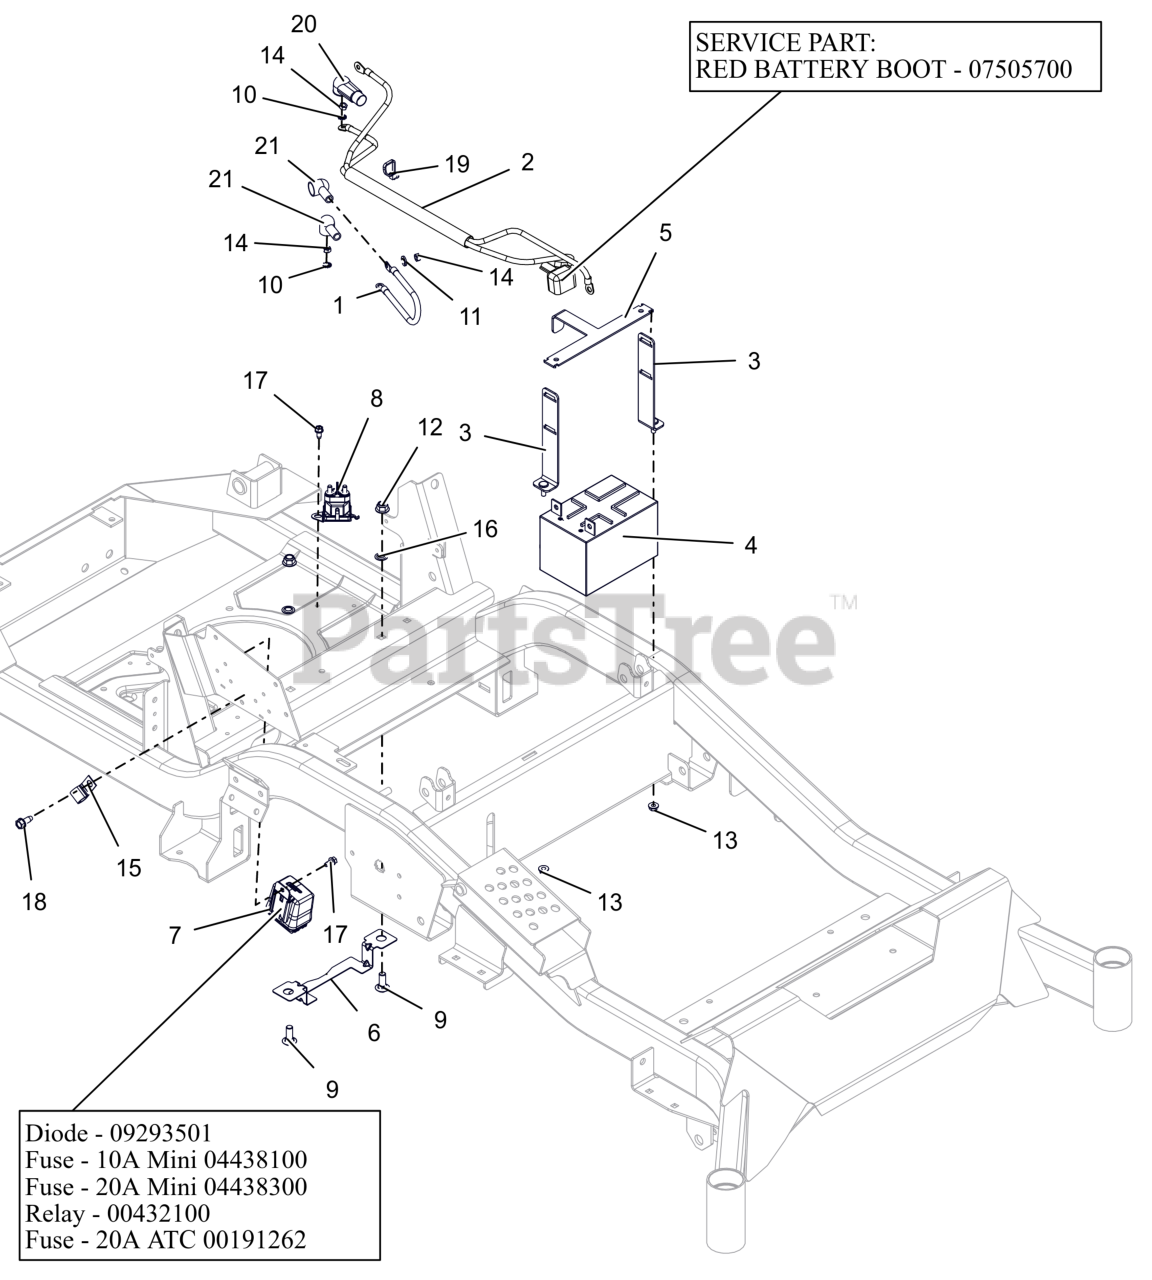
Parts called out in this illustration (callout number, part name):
1	CABLE, POS W/(2)1/4 RING 9.0LG
2	HARNESS, BATTERY HD
2	INSULATOR
3	WMT,BATTERY MOUNT HOLD DOWN
4	BATTERY, 12V 12A-190CCA
5	BRKT, BATTERY TIE DOWN
6	GUARD, ELECTRICAL HARNESS
7	HARNESS, WIRE
7	DIODE, CONNECTOR SHELL
7	FUSE,10 AMP MINI-ATC
7	FUSE,20 AMP MINI ATC
7	RELAY,SEALED W/DIODE
7	FUSE, 20 AMP BLADE S/O
8	SOLENOID, STARTER (SEALED)
9	BLT, RHSN .38-16X1.00 G5 ZCC
10	WSHR,LK-EXT.262X.502X.026 ZCC
11	WSHR,LK-REG .312X.078 ZCC
12	NUT,NYL-FLG .38-16 GF ZCC
13	NUT-LK-TOP-FLG .250-20 GF ZCC
14	NUT-STD M6-1.0 ZCC
15	J-CLAMP
16	NUT-PUSH .38 DIA. PAL ZINC
17	SCR-TAP .25-20X.50 HWH ZCC
18	SCR,TAP .312-18X.75 HWH TR ZCC
19	CABLE TIE W/ TREE (.25 HOLE)
20	BOOT, .65ID POS
21	BOOT, EYELET TERMINAL
